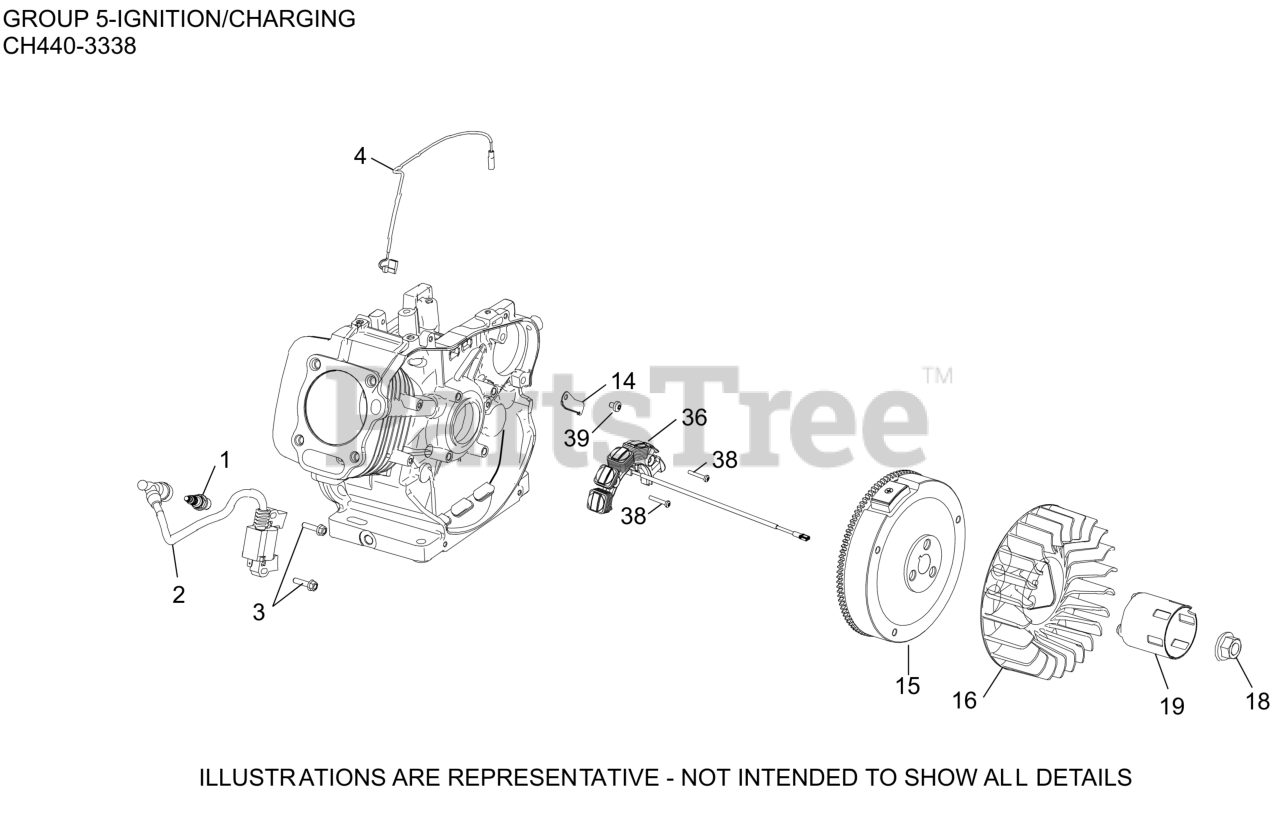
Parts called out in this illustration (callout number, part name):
1	SPARK PLUG
2	MODULE, IGNITION
3	SCREW, M6 X 25-(#25086436S)
4	LEAD, GROUND TO KILL
14	BRACKET, STATOR WIRE
15	FLYWHEEL ASSY ELECTRIC START (CH440)
16	FAN, FLYWHEEL
18	NUT, FLYWHEEL
19	CUP, STARTER DRIVE
36	STATOR ASSEMBLY, 1 AMP
38	SCREW, STATOR MOUNTING
39	SCREW, COIL BRACKET
